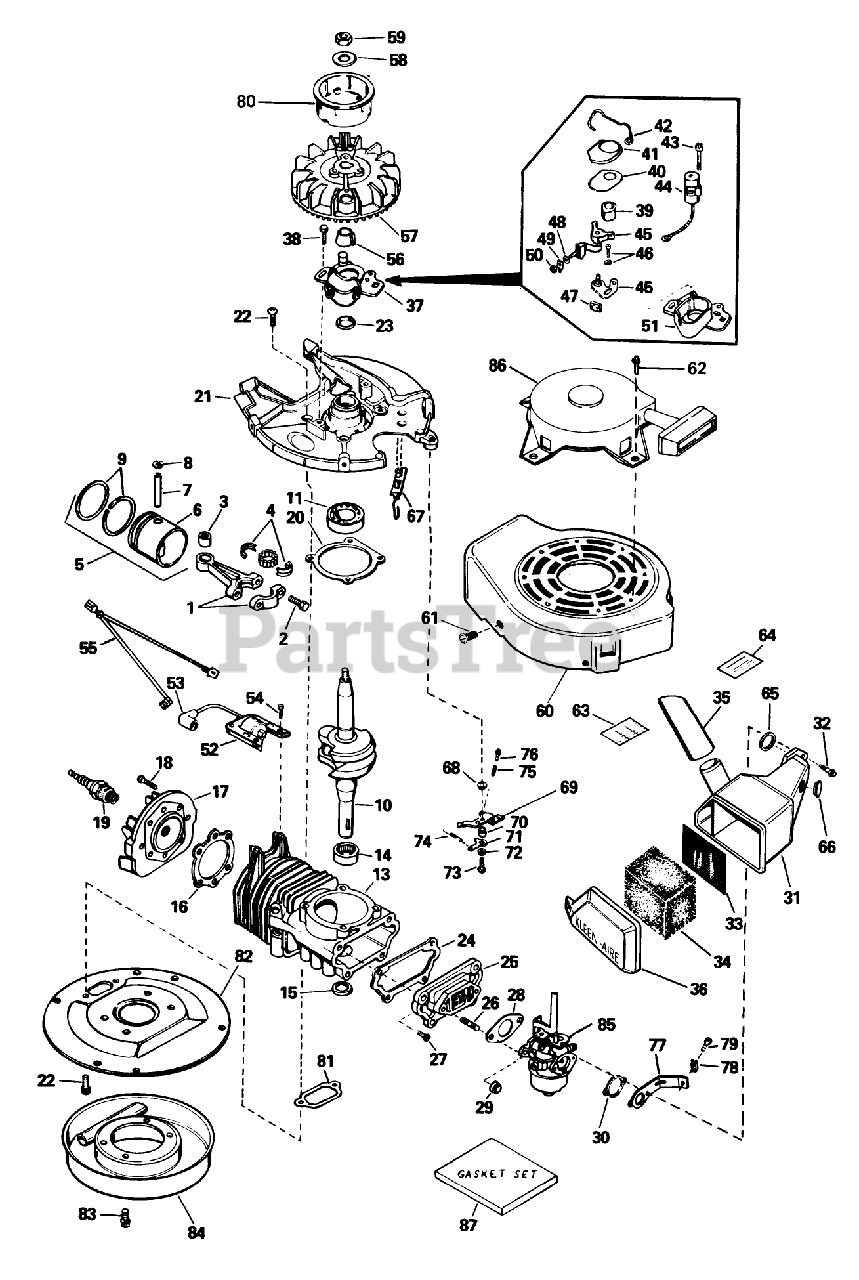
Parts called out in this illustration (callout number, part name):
1	Rod Assy., Connecting (Incl. Ref. #2, 3 4)
2	Bolt-Rod, Connecting
3	Bearing-Cartridge
4	Bearing Liner Set-Needle
5	Piston, Pin Ring Assy. (Incl. Ref. #6 thru 9)
6	Piston
7	Pin, Piston
8	Ring-Retaning
9	Ring Set
10	Crankshaft
11	Bearing-Ball
13	Block Assy., Cylinder (Order short block if replacement is requlred)
14	Bearing, Cartridge
15	Seal, Crankshaft
16	Gasket, Head
17	Head-Cylinder
18	Screw (T-30, 1/4-20 x 3/4)
19	Plug, Spark (Champion RCJ-8)
20	Gasket, Shroud Base
21	Base Assy., Housing (Incl. Ref. #23)
22	Screw
23	Seal-Oil
24	Gasket, Reed Plate
25	Plate Assy., Reed (Incl. No. 22)
26	Stud Carburetor
27	Screw (T-25, 10-24 x 1/2)
28	Gasket, Carburetor
29	Locknut
30	Gasket
31	Body, Air Cleaner
32	Screw
33	Screen, Air Cleaner
34	Element, Air Cleaner
35	Tube, Air Cleaner
36	Cover, Air Cleaner
37	Stator Plate Assy. (incl. Nos. 107, 111 thru 118 120)
38	Screw, Hex Washer Hd.
39	Cam, Breaker
40	Gasket, Dust Cover
41	Cover-Dust
42	Spring Breaker Box
43	Condenser Screw
44	Condenser
45	Breaker Assy.
46	Breaker Screw
47	Felt,Cam Wiper
48	Washer
49	Terminal, Ground
50	DECAL
51	Stator Plate
52	Lamination Coil Assy. (Incl. No. 42)
53	Cover-Spark Plug
54	Screw
55	Wire, Cut Off
56	SHIELD
57	FIywheel
58	Washer-Spring
59	Nut-Flywheel
60	Housing, Blower
61	Screw-Hex, Hd.
62	Rivet (Can be purchased locally)
63	Decal, Fuel Mix
64	Decal, Warning
65	Gasket-Cleaner, Air
67	Terminal
68	Washer
69	Lever, Control
70	Spacer
71	Lever, Adjusting
72	Washer
73	Screw, Pan Flex Hd.
74	Spring, Governor
75	Spring-Compression
76	Screw
77	Bracket, Boden Wire
78	Conduit
79	Screw (10-32 x 3/8)
80	Cup-Starter
81	Gasket, Exhaust
82	Ring, Adapter
83	Screw, Flanged Hex Hd.
84	Muffler
85	Carburetor (Incl. Ref. #28)
86	Starter, Rewind
87	Gasket Set
